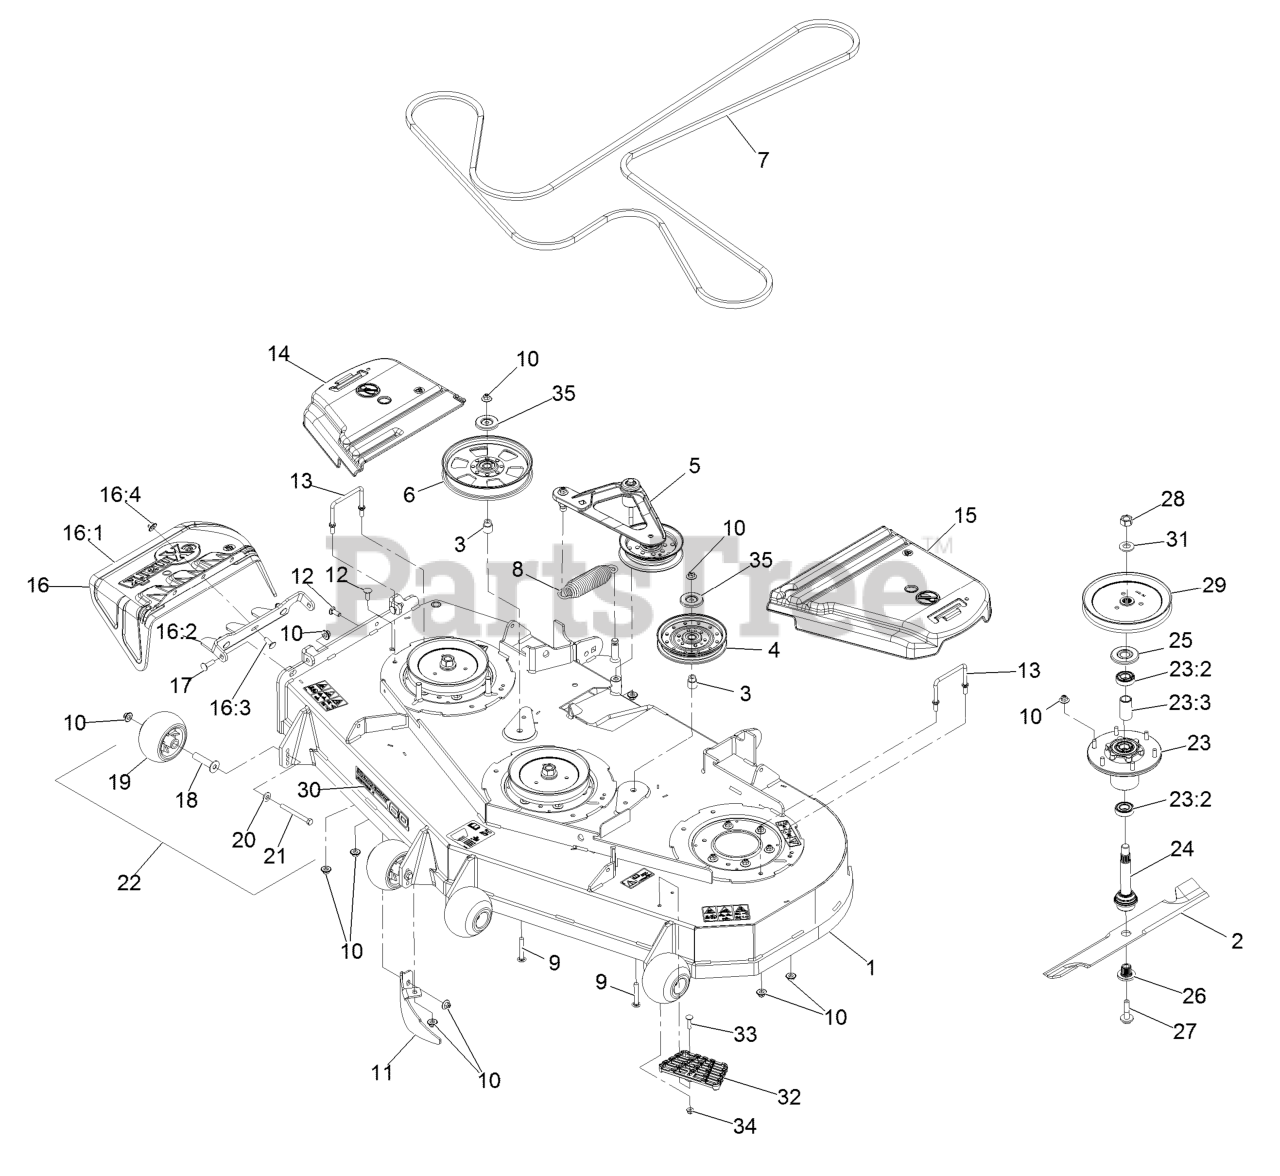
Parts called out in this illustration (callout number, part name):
1	DECK ASM,W/DECALS 60
2	Blade-Extreme 2, 20.50"
3	BUSHING-IDLER
4	IDLER-PULLEY
5	DECK IDLER ASM
6	PULLEY-IDLER, FLAT
7	BELT,V-5V-198.75
8	SPRING-EXTENSION
9	SCREW-CARR
10	Nut-Nyloc 3/8-16 Flg
11	DOGLEG - LZ60
12	SCREW-CARR
13	WIREFORM-COVER
14	COVER-BELT, RH
15	COVER-BELT, LH
16	ASM,DISCHARGE CHUTE
16:1	CHUTE,DISCHARGE
16:2	BRACKET,DISCHARGE CHUTE
16:3	SCREW-CARR
16:4	Nut-Nyloc 3/8-16 Flg
17	Bolt-Carriage 3/8-16 X 1 1/4
18	AXLE, ROLLER
19	ROLLER-SCALP, ANTI
20	WASHER-BELLEVILLE
21	SCREW-HH 3/8-16 X 3 3/4 GR 8
22	KIT, ANTI-SCALP ROLLER
23	ASM-CUTTER HSG WITH BEARINGS
23:2	BEARING-BALL
23:3	SPACER-BEARING
24	ASM-SPINDLE AND SEAL
25	GUARD,BEARING TOP .989
26	BUSHING,SPLINED
27	SCREW,SEMS 1/2-20 X 2.19
28	NUT-HEX
29	SHEAVE,BLADE DRIVE 7.25
30	DECAL, 604
32	STEP-DECK
33	Bolt-Carriage 5/16-18 X 1 1/4
34	NUT-HF, NI
35	SHIELD-DUST
